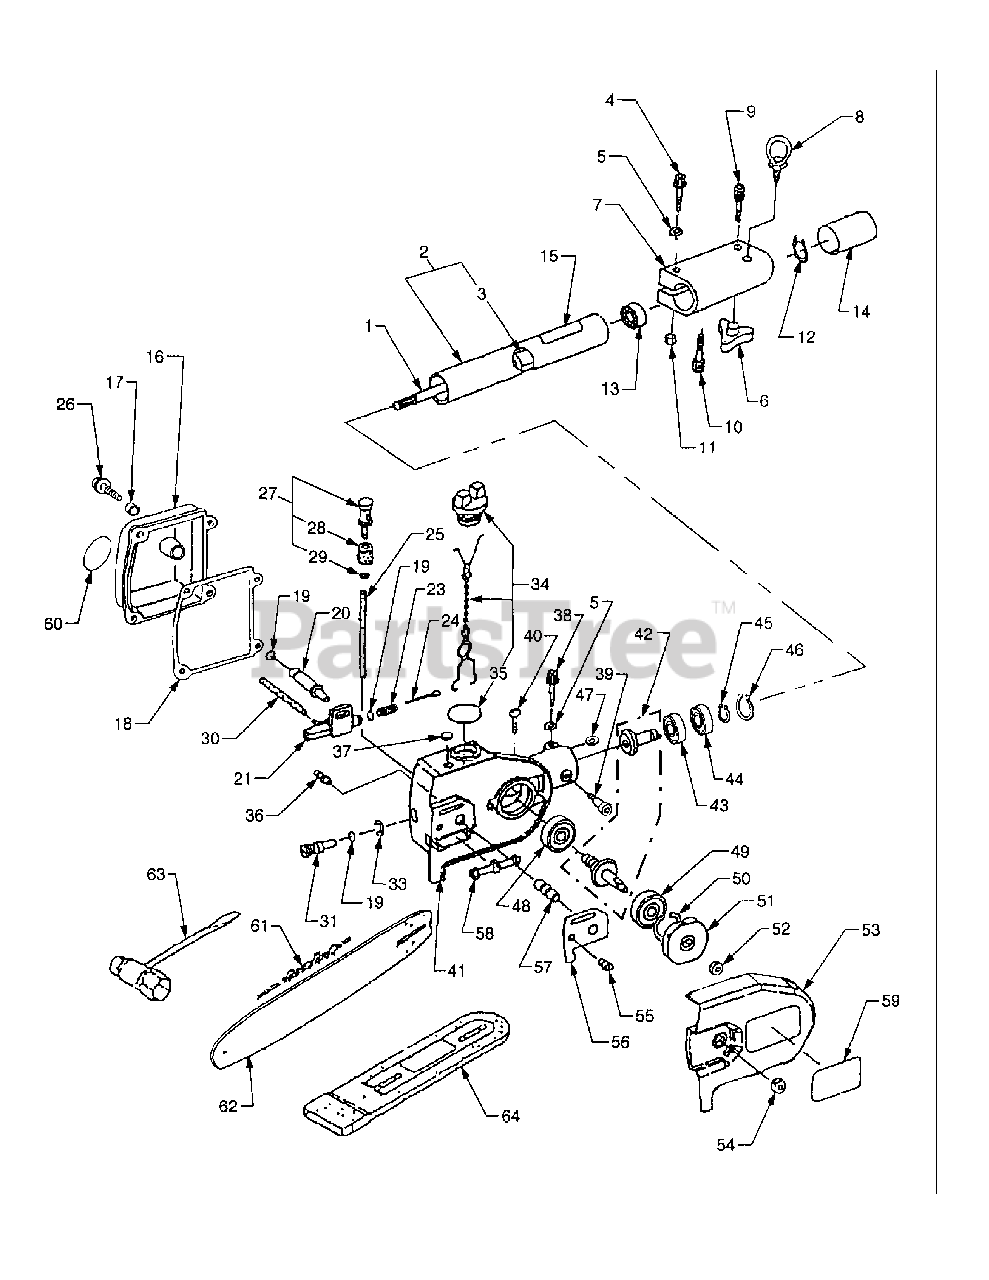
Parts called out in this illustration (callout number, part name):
1	Shaft, Drive
2	Pipe Complete
5	Washer, Spring
6	Nut, Knob
7	Case, Joint
8	Pin, Lock
12	Ring, Snap
13	Bearing, Ball
15	Caution Plate
16	Cover, Oil Tank
21	Pump, Lube Oil
24	Piston, Oil Pump
27	Filter Ass'y., Oil
28	Filter, Oil
29	Washer
31	Adjuster, Oil Pump
33	Ring, Snap
34	Cap, Oil Filler
36	Connector
41	Case, Gear
42	Gear Assembly
43	Bearing, Ball
44	Bearing, Ball
45	Ring, Snap
46	Ring, Snap
48	Bearing, Ball
49	Bearing, Ball
50	Ring, Snap
51	Sprocket
55	Pin, Dowel
56	Plate, Guide
59	Name Plate
60	Caution Plate
61	Chain, 9.52mm
62	Bar, Chain, 250mm
63	Box, Spanner
64	Cover, Chain
